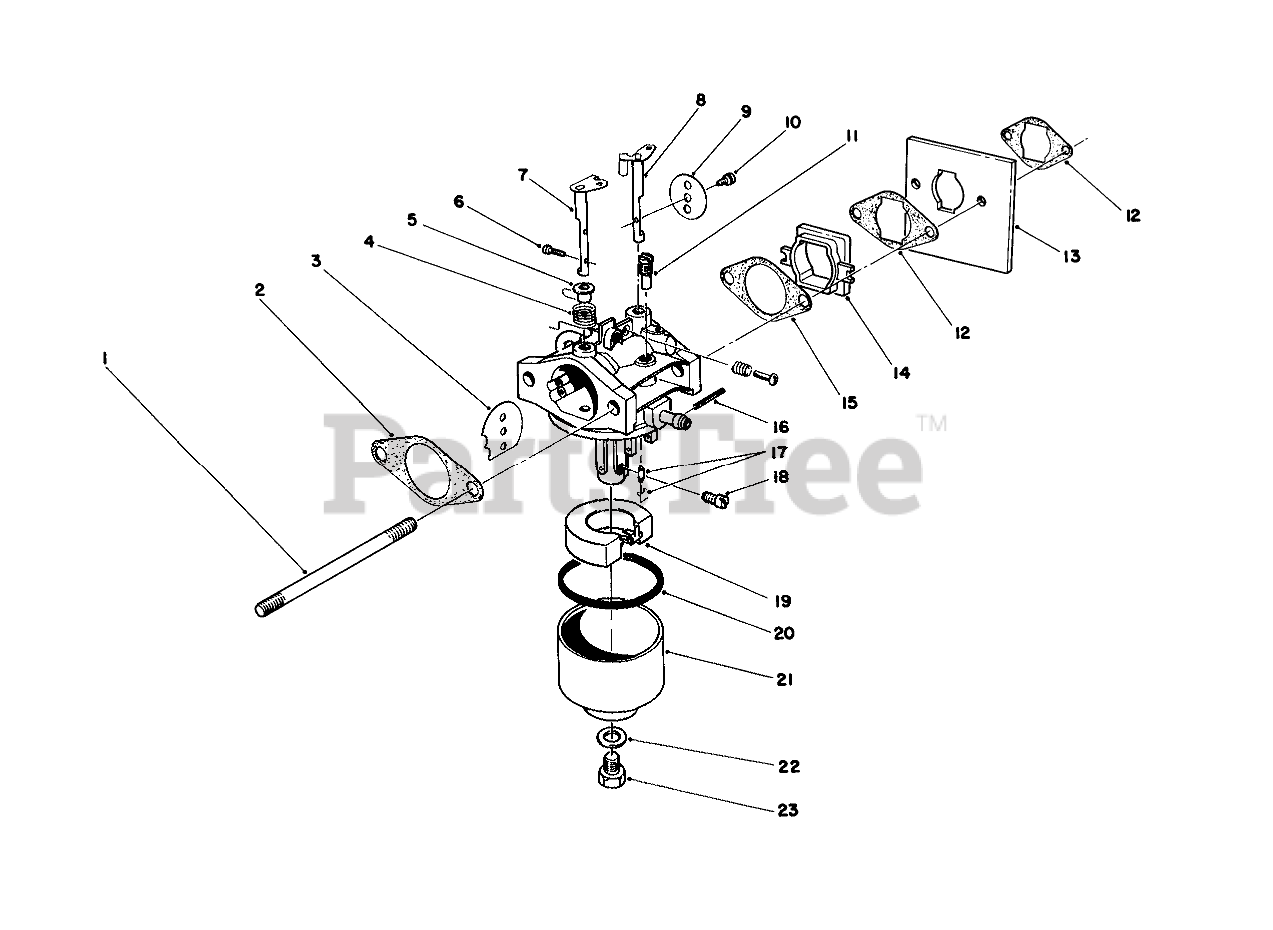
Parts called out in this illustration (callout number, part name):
1	CARB STUD BOLT
2	GASKET-AIR CLEANER
3	PLATE
4	SPRING
5	BUSHING
6	SCREW
7	SHAFT-CHOKE
8	SHAFT
9	PLATE
10	Screw-Throttle
11	PILOT JET
12	GASKET
13	SHIELD
14	INSULATOR
15	GASKET-CARB
16	Pin
17	NEEDLE VALVE ASM
18	MAIN JET (76.3)
19	FLOAT
20	GASKET
21	Bowl-Float
22	GASKET
23	Bolt
